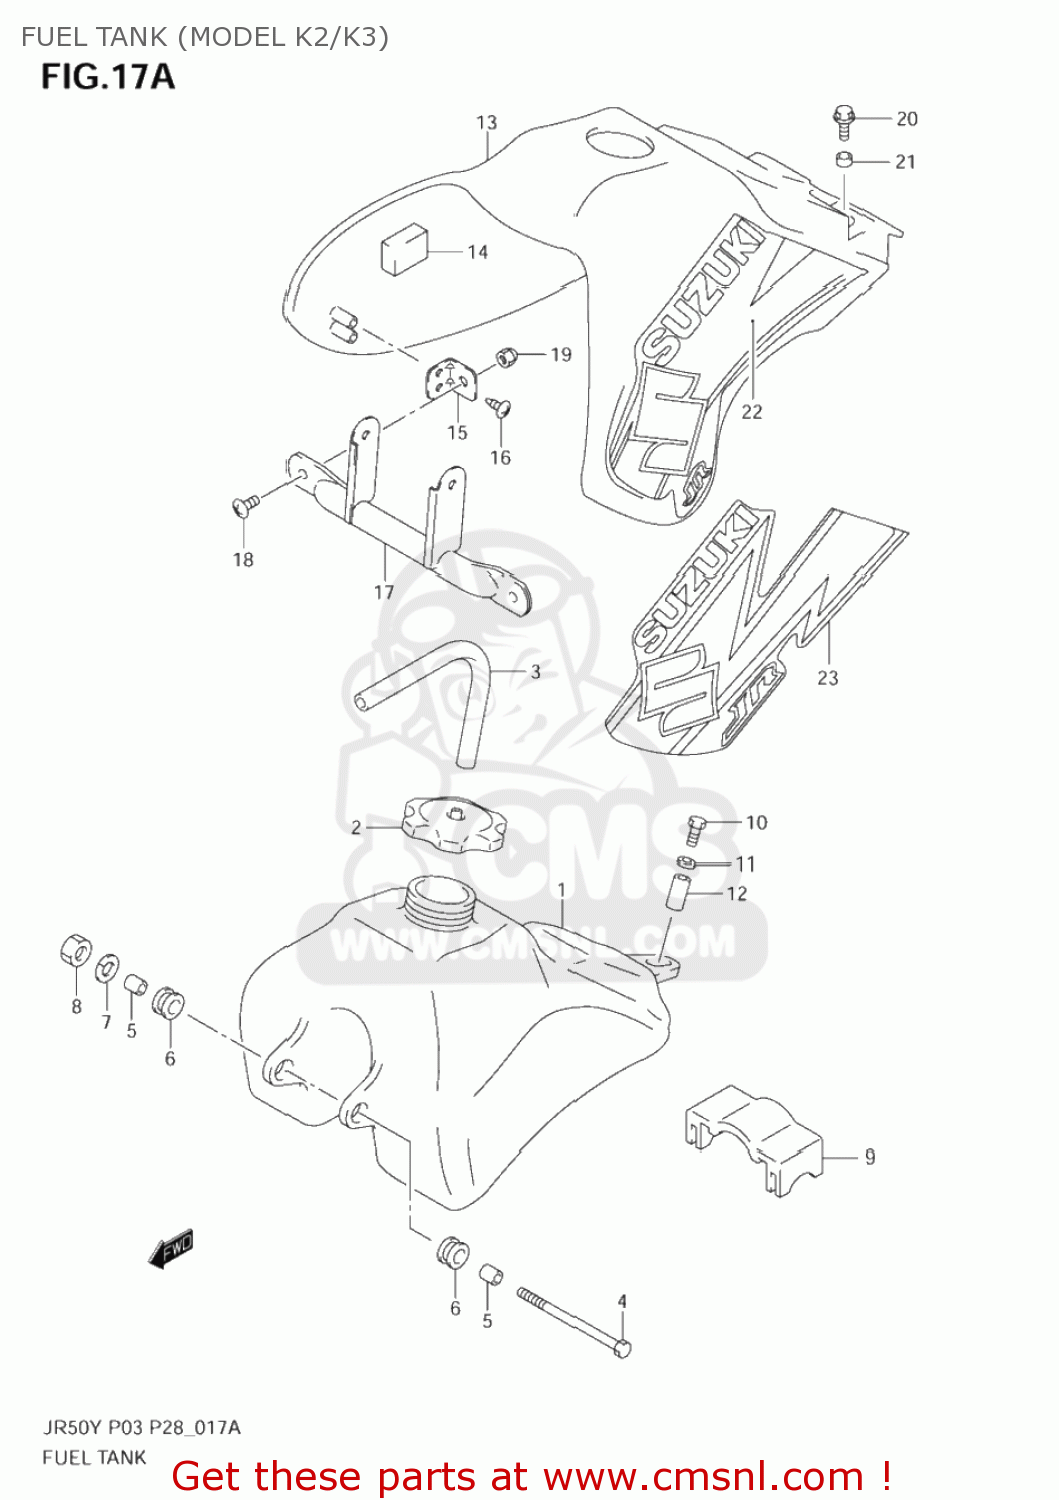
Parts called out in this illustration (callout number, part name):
1	TANK ASSY,FUEL
2	CAP ASSY,FUEL TANK FILLER
3	HOSE(5X8.2X600)
4	BOLT, FRONT
5	SPACER(6.5X10X11.5)
6	CUSHION
7	LOCK WASHER
8	NUT 6MM
9	CUSHION,FUEL TANK UPR
10	BOLT
11	WASHER(6.5X18X1)
12	SPACER(6.5X9X7.2)
13	COVER,FUEL TANK
14	CUSHION,RADIATOR COVER FR
15	BRACKET,FUEL TANK COVER NO.1
16	SCREW
17	BRACKET,FUEL TANK COVER
18	SCREW 6X12
19	NUT
20	SCREW(6X16)
21	SPACER(6.5X10X5)
22	TAPE SET,FUEL TANK COVER
23	TAPE SET,FUEL TANK COVER
